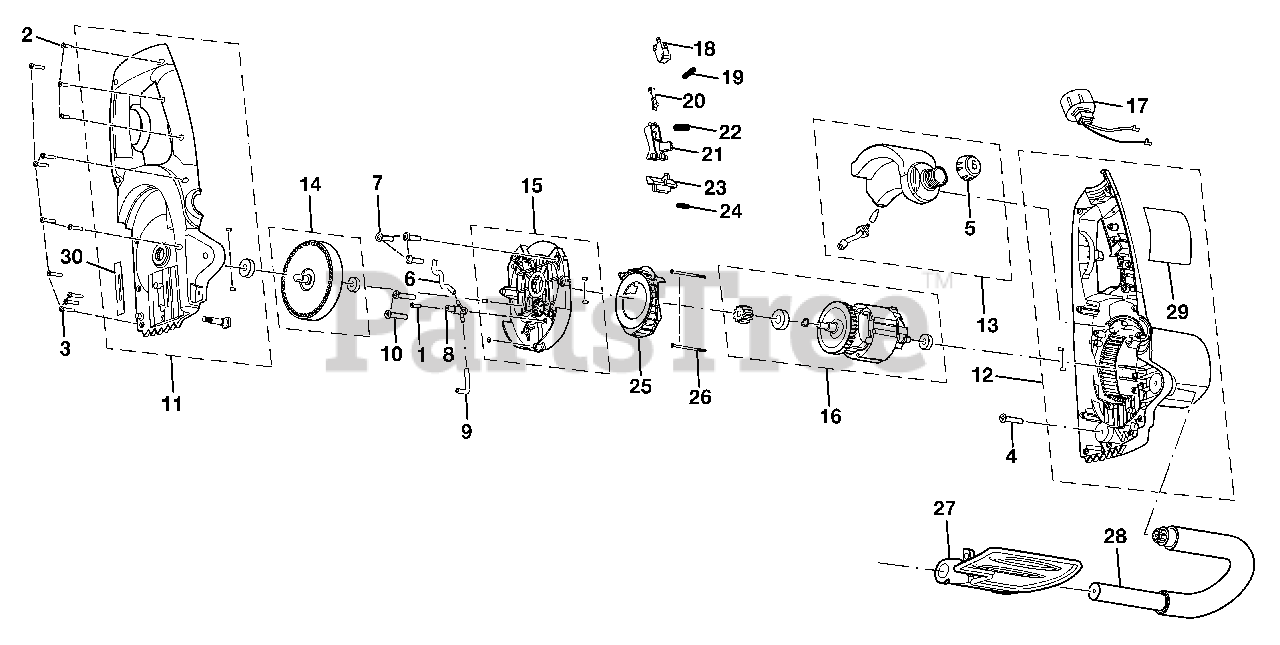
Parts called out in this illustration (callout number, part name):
1	SCREW (M4 X 12 mm PAN HD.)
2	SCREW (M4 X 14 mm PAN HD.)
3	SCREW (M4 X 22 mm PAN HD.)
4	SCREW (M4.5 X 22 mm PAN HD.)
5	OIL RESERVOIR CAP
6	LONG OIL TUBE
7	SCREW (M4.5 X 14 mm PAN HD.)
8	OIL PUMP ASSEMBLY
9	SHORT OIL TUBE
10	SCREW (M4.5 X 18 mm PAN HD.)
11	HOUSING COVER ASSEMBLY
12	HOUSING SUPPORT W/ LABEL ASSEMBLY
13	OIL TANK ASSEMBLY
14	GEAR ASSEMBLY W/ BEARING
15	GEAR CASE ASSEMBLY
16	MOTOR ASSEMBLY W/ BEARING
17	RECEPTACLE & RECESS PLUG ASSEMBLY
19	SPRING (°0.5 X ID4.5 X 23)
20	SWITCH LEVER
22	MAIN TRIGGER SPRING (°8 X OD7.9 X 34)
23	LOCK OFF BUTTON
25	FAN BAFFLE
26	SCREW (#8 X 2-1/8 in. PAN HD.)
27	SAFETY GUARD
28	FRONT HANDLE
29	DATA LABEL
30	RUBBER SEAL
